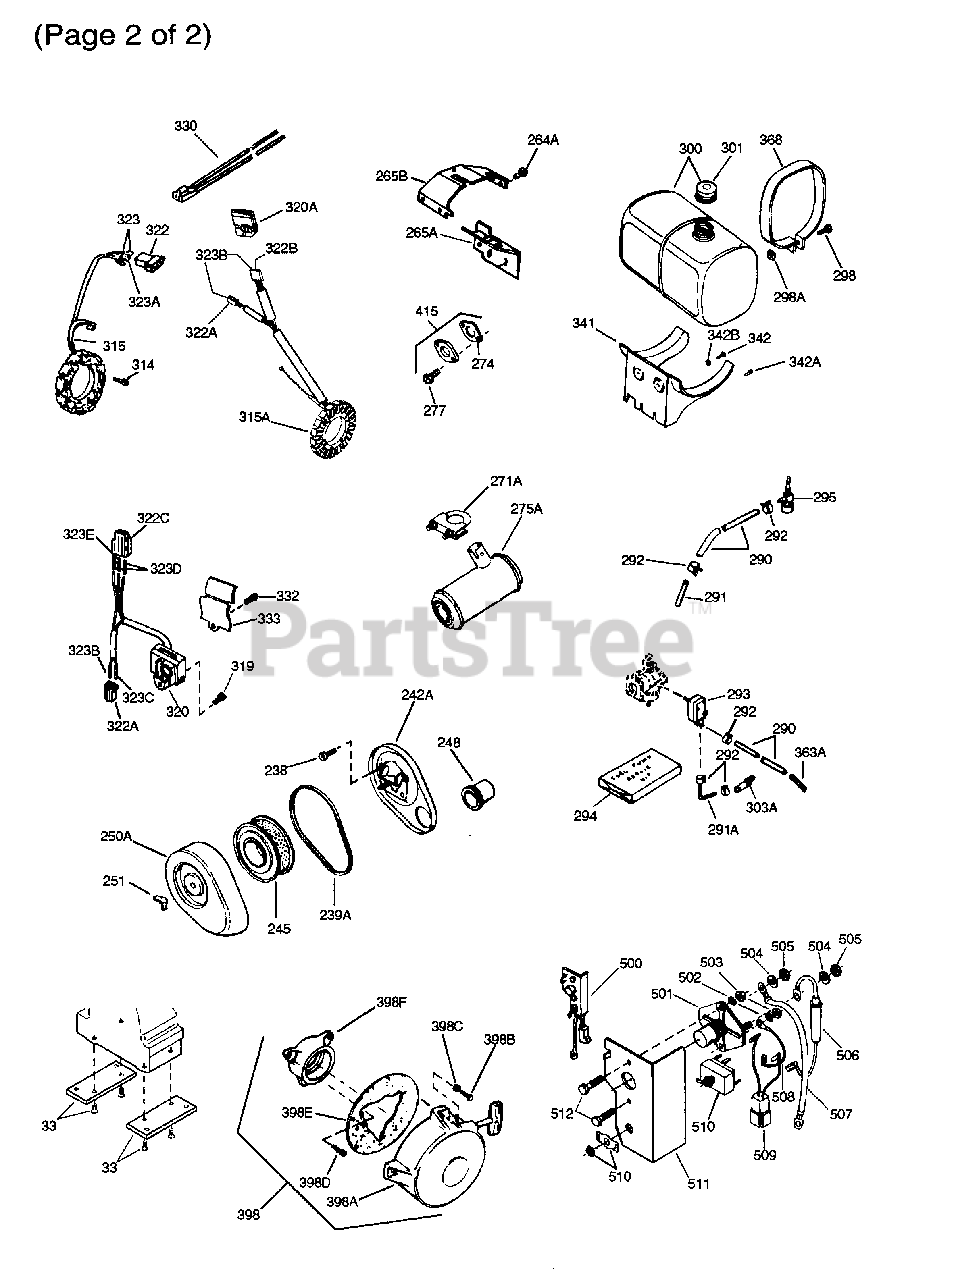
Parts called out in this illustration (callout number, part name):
16B	Governor Spring Plate
72B	Oil Drain Plug
238	Screw, 10-32 x 5/8"
239A	Air Cleaner Gasket
245	Air Filter
248	Air Cleaner Tube
251	Wing Nut, 1/4-20
261A	Screw, 1/4-20 x 7/16"
271A	Muffler Clamp
274	* Exhaust Gasket
290	Fuel Line (8.62")
291	Fuel Line
291A	Fuel Line (8.62")
292	Fuel Line Clamp
293	Pulse Pump
294	Pulse Pump Repair Kit (Walbro pumps o nly)
295	Fuel Shut-Off Valve
298	Screw, 1/4-20 x 1-1/4"
298A	Lock Nut, 1/4-20
300	Fuel Tank (Incl. 301)
301	Fuel Cap (Red 1-1/2" ID) also availab le in Packaged Part #740005B
303	Fuel Fitting
311	Oil Fill Plug (Incl. 312)
312	"O" Ring
314	Screw, 10-32 x 1-1/8"
315	Alternator Coil (20 Amp) Incl. 322 32 2A&323
319	Screw, 1/4-20 x 1/2"
320	Regulator (20 Amp)
322	Connector Body
322A	Connector Body
323	Terminal
341	Fuel Tank Bracket
342	Screw, 1/4-20 x 5/8"
342A	Screw, 5/16-18 x 5/8"
342B	Belleville Washer
355	Starter Handle
368	Fuel Tank Strap
500	Switch Ass'y.
501	Starter Switch
503	Nut, 1/4-20
504	Lock Washer
505	Nut, 5/16-24
506	Wire & Fuse
507	Starter Wire
508	Ground Wire
509	Adapter Cord
509A	Alternator Adapter Cord
510	Toggle Switch
511	Starter Button Bracket
512	Screw, 1/4-20 x 7/8"
